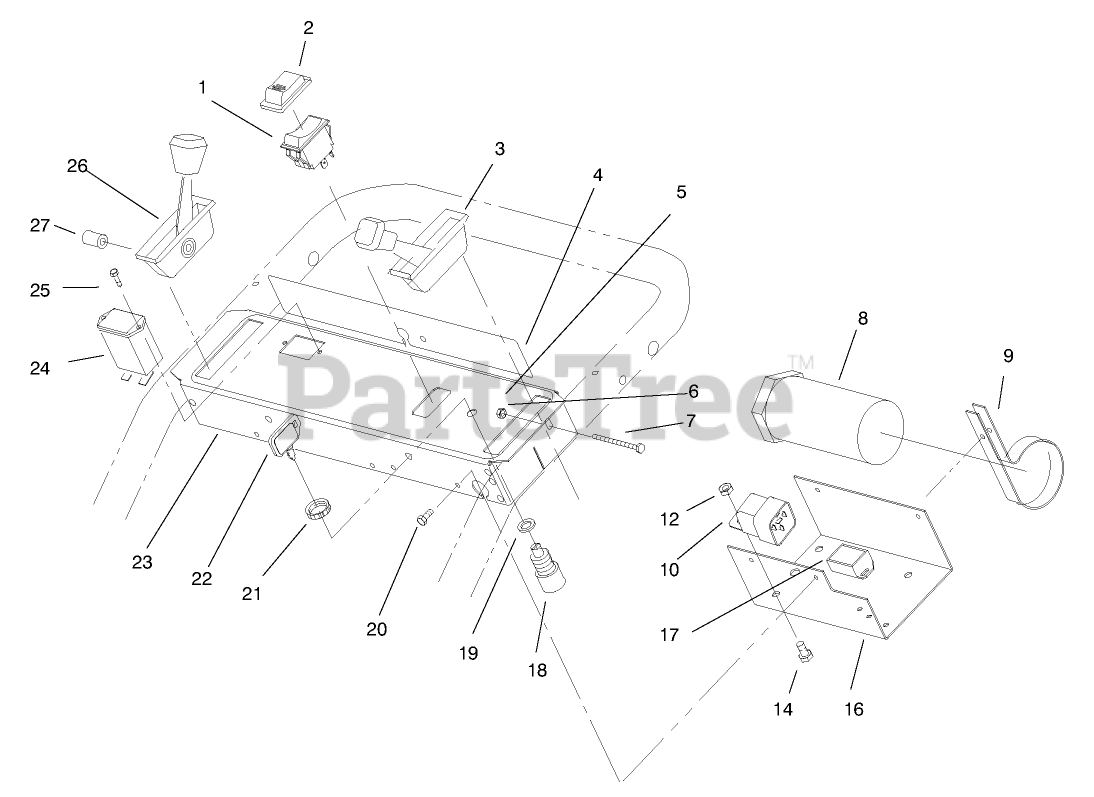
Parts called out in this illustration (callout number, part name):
1	SWITCH
2	BOOT-SWITCH
3	CONTROL - THROTTLE
4	DECAL-WARNING
5	DECAL - CONTROL PANEL
6	NUT-LOCK, NI
7	SCREW-SHH
8	TUBE-MANUAL
9	CLAMP-R
10	RELAY
12	NUT-LOCK, NI
14	SCREW-HH
16	PANEL-BOTTOM
17	MODULE
18	SWITCH-STARTER
19	WASHER-TOOTH, INTERNAL
20	SCREW-HWHTF
21	NUT-HH
22	KEY-IGNITION
23	PANEL - CONTROL
24	HOURMETER
25	SCREW-HWH
26	CONTROL - CHOKE
27	SPACER
